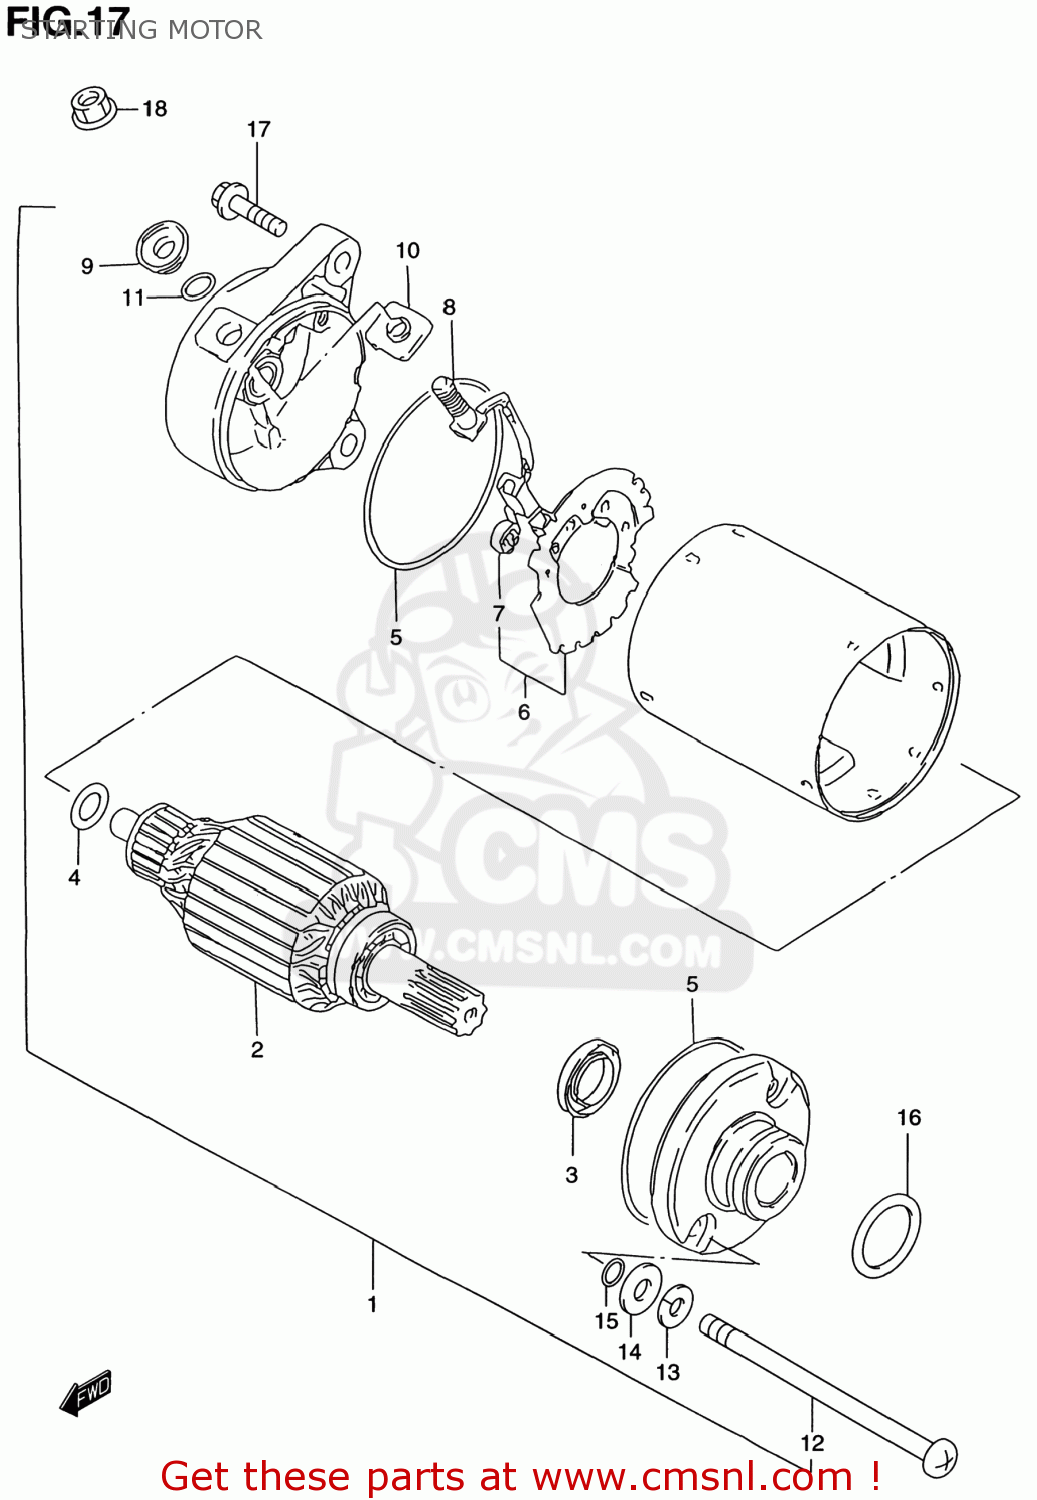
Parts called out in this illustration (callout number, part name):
1	MOTOR ASSY,STARTING
2	ARMATURE
3	SEAL,OIL
4	SHIM SET,STARTING MOTOR
5	O RING
6	HOLDER,BRUSH
7	SPRING
8	BRUSH SUB ASSY,STARTING MOTOR
9	BUSHING
10	BUSH,B
11	O RING
12	BOLT
13	WASHER,LOCK
14	WASHER
15	O RING
16	O RING(D:3,ID:24.5)
17	BOLT
18	NUT
